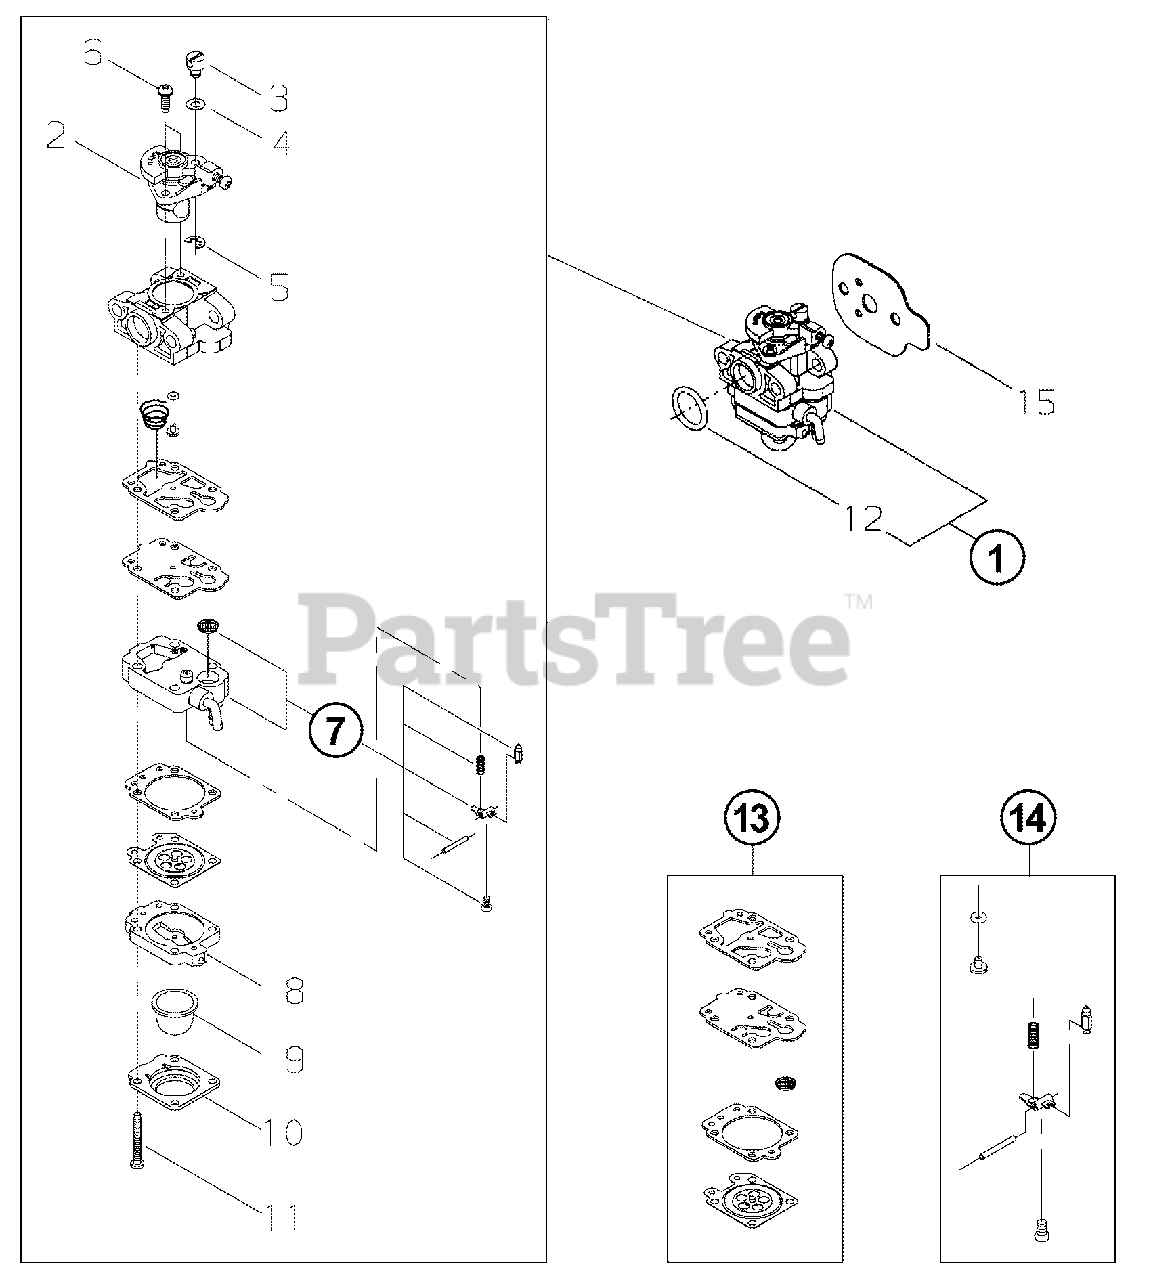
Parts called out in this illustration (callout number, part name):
1	CARBURETOR
2	VALVE ASSY, THROTTLE
3	SWIVEL
4	WASHER
5	E-RING
6	SCREW, THROTTLE COLLAR
7	BODY ASSY, PUMP
8	BODY ASSY, PURGE
9	BULB, PURGE
10	RETAINER, PURGE BULB
11	SCREW
12	O-RING 15
13	GASKET / DIAPHRAGM KIT
14	SWITCH, ON-OFF
15	GASKET, INTAKE
